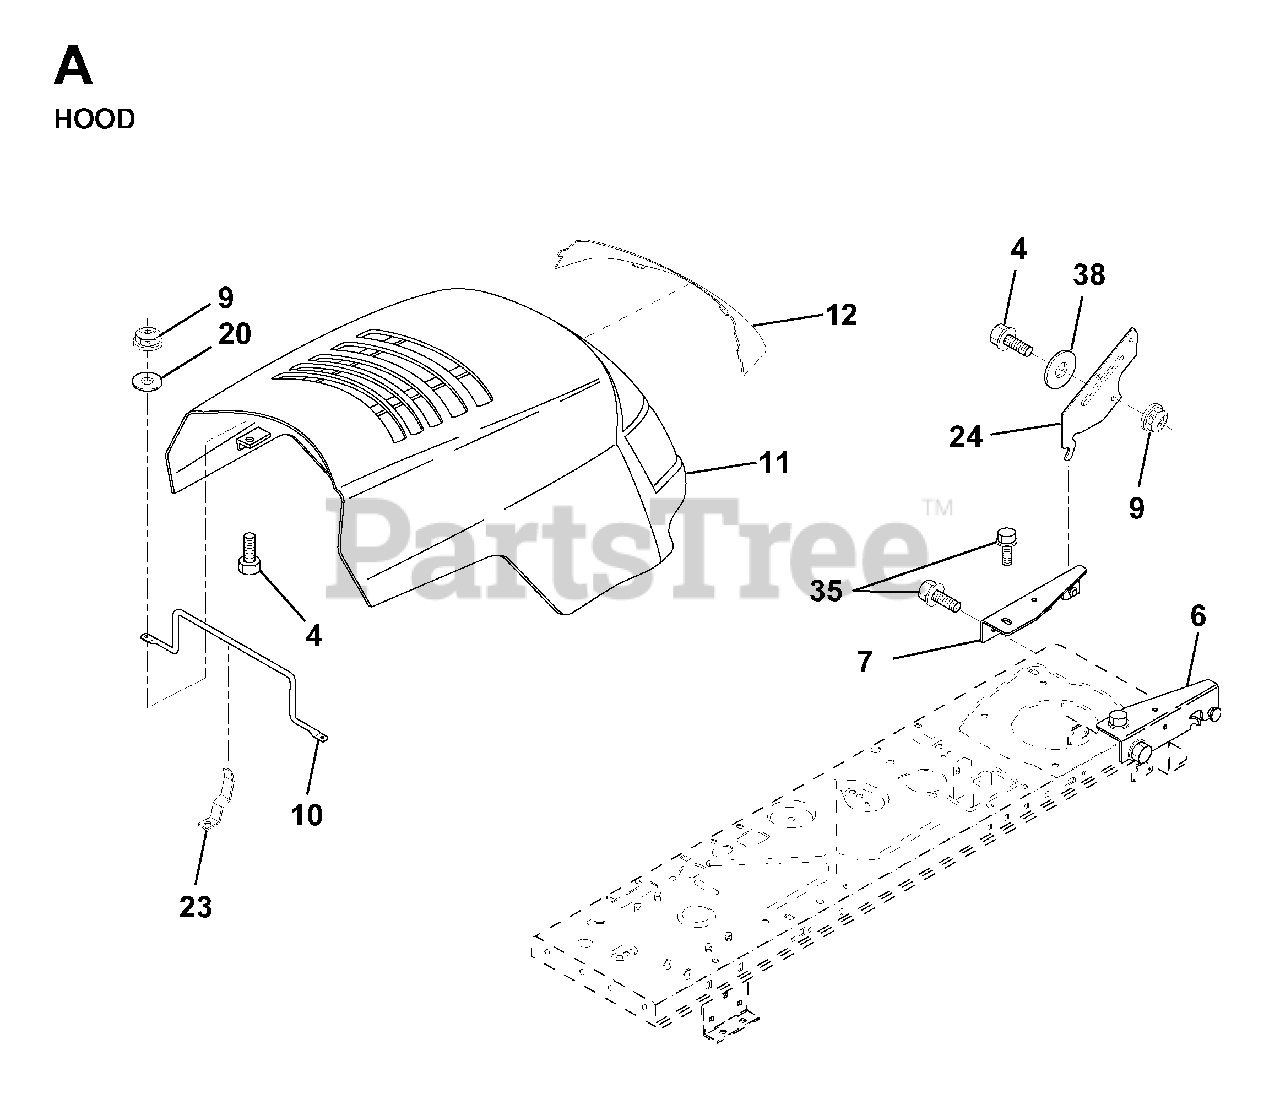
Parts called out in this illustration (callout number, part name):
4	BOLT
6	BRACKET ASSY HOOD
7	BRACKET ASSY
9	LOCKNUT
20	WASHER
23	HOOD LATCH
35	SCREW
